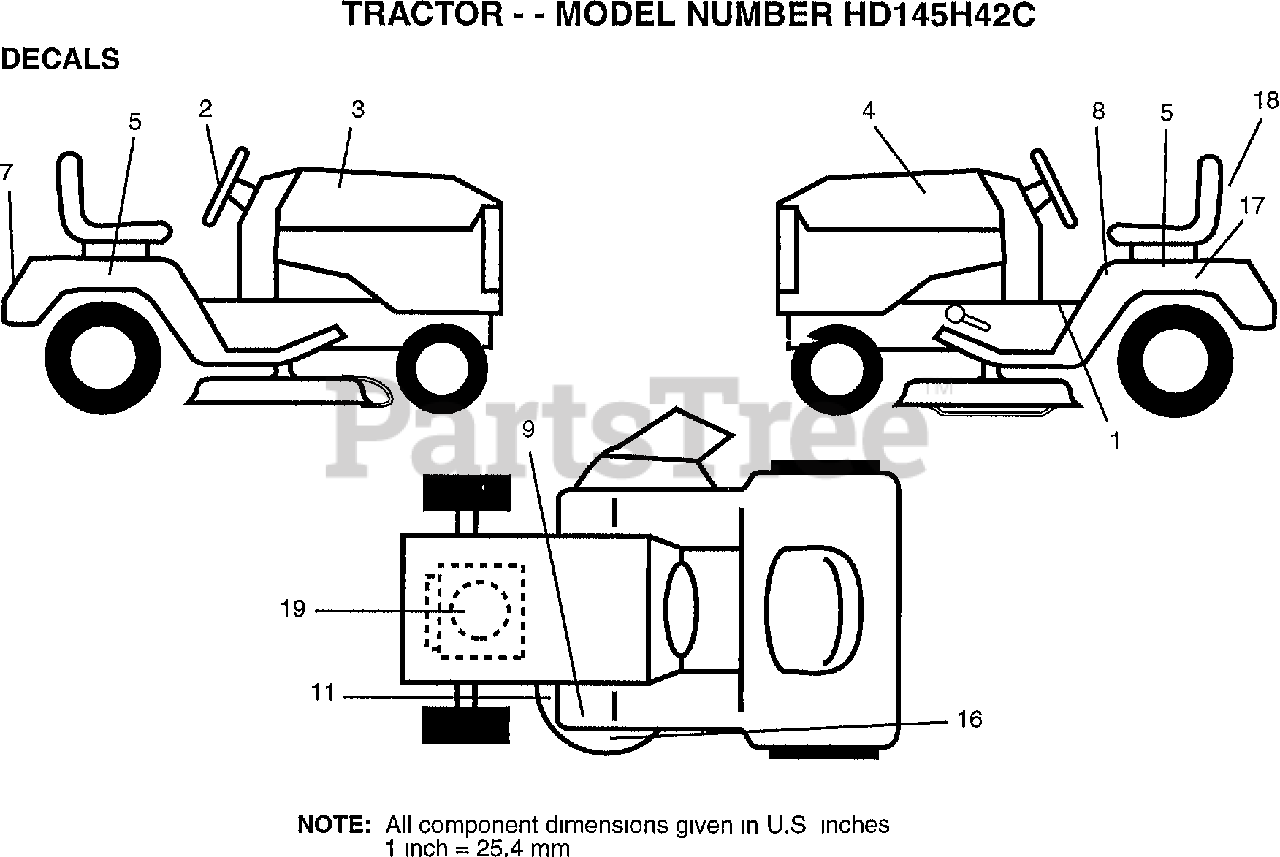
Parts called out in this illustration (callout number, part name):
1	"DECAL-SADDLE,INST"
2	"DECAL WHEEL,STEER"
3	"DECAL-HOOD,RH"
4	"DECAL-HOOD,LH"
5	"DECAL FENDER,SD"
7	"DECAL FENDER,LOGO"
8	"DECAL FENDER,DANG"
9	DECAL CLUT/BRAKE
11	DECAL
16	"DECAL DECK,MULCH"
17	DECAL.BATRY.3-3908
18	"DECAL SEAT,ACC"
19	"DECAL REPLCMT,ENG"
